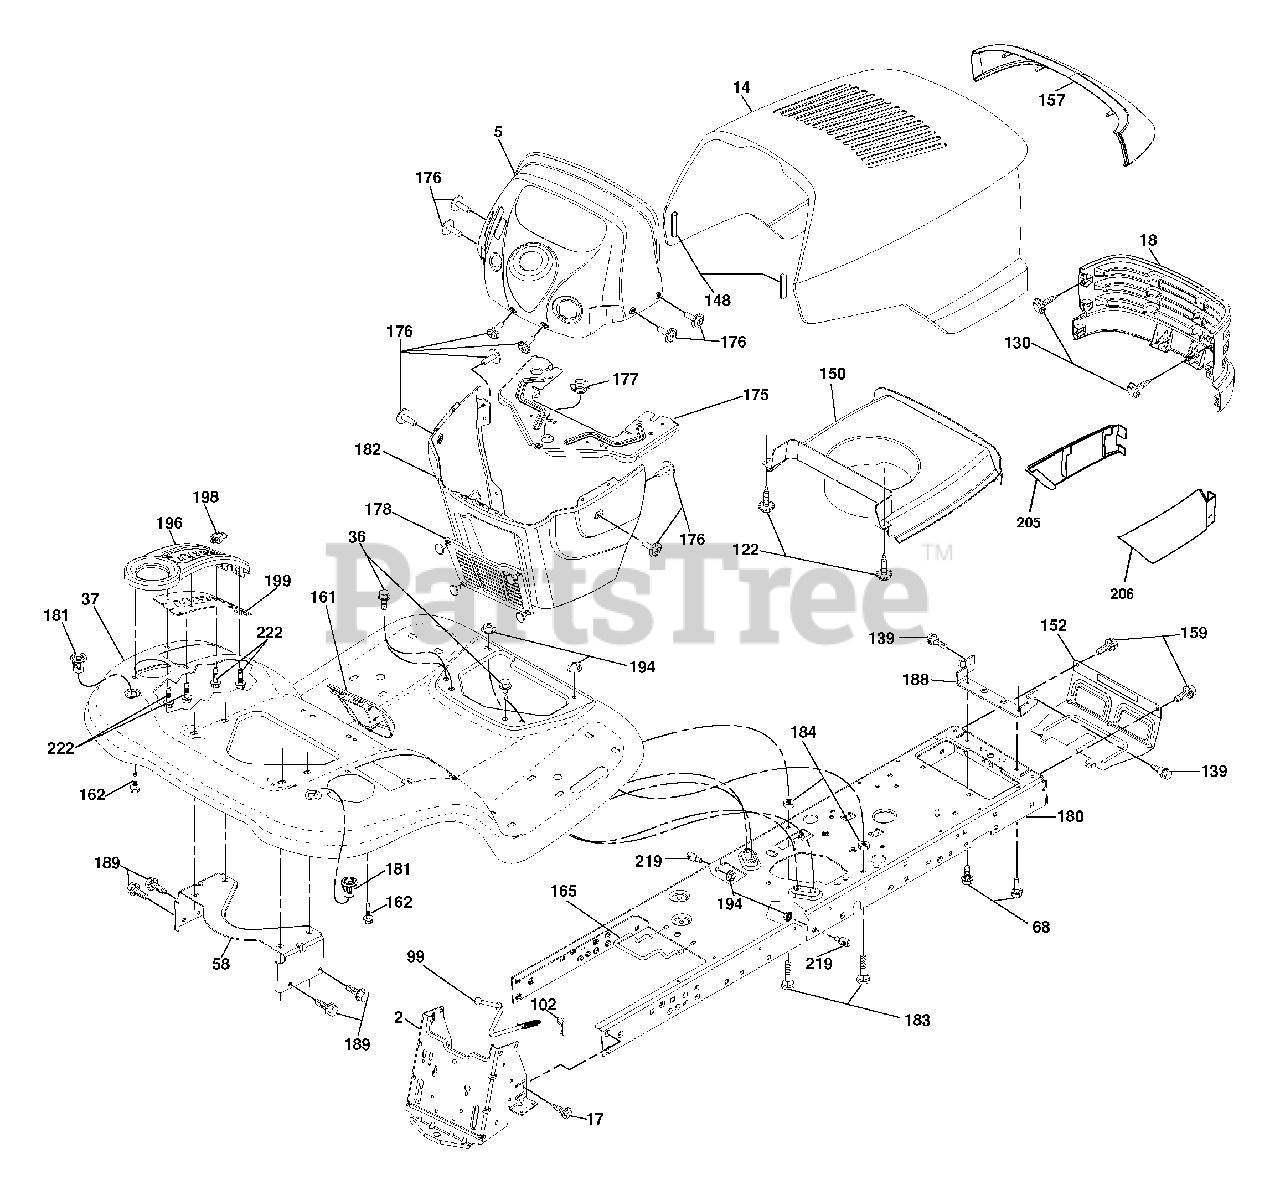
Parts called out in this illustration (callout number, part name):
5	Dash
14	Hood
17	Screw 3/8-16 x .75
18	Grille
36	Screw 5/16-18 x 3/4
37	Fender
58	Bracket Fender
68	Screw Thdrol 5/16-18 x 1/2
99	Rod Bypass Asm.
102	Retainer Spring 1"
122	Screw WSHD Hex 10-32 x 5/8
130	Screw 10 x 3/4 Single Lead-Hex
139	Bolt Shoulder 5/16-18
148	Bumper
150	Duct Heat Hood
152	Shield Browning/Debris
157	Lens Bar
159	Screw Hexwsh Thdrol 3/8-16 x 3/4
161	Console Fuel Window
162	Screw Hex Wsh Hi-Lo 1/4 x 1/2
165	Bracket Support Tank
175	Crossmember
176	Screw #10-24 x 5/8 Rnd Qudrx
177	Bushing Steering
178	Cargo Asm. Net
181	Bushing Mtg. Fender Crgo.
182	Dash Lower
183	Bolt Fin Hex 5/16-18UNC x 1-1/4
184	Spacer Fender
188	Bracket Pickoff Hood
189	Screw 5/16-18 x 3/4
194	Nut Lock Hex Flange 5/16-18
196	Console Asm. Deck Lift
198	Indicator Deck Lift
199	Plate Deck Lift
205	Skirt Hood RH
206	Skirt Hood LH
219	Stud Fastener
222	Screw thd Roll 1/4-20 x 5/8
